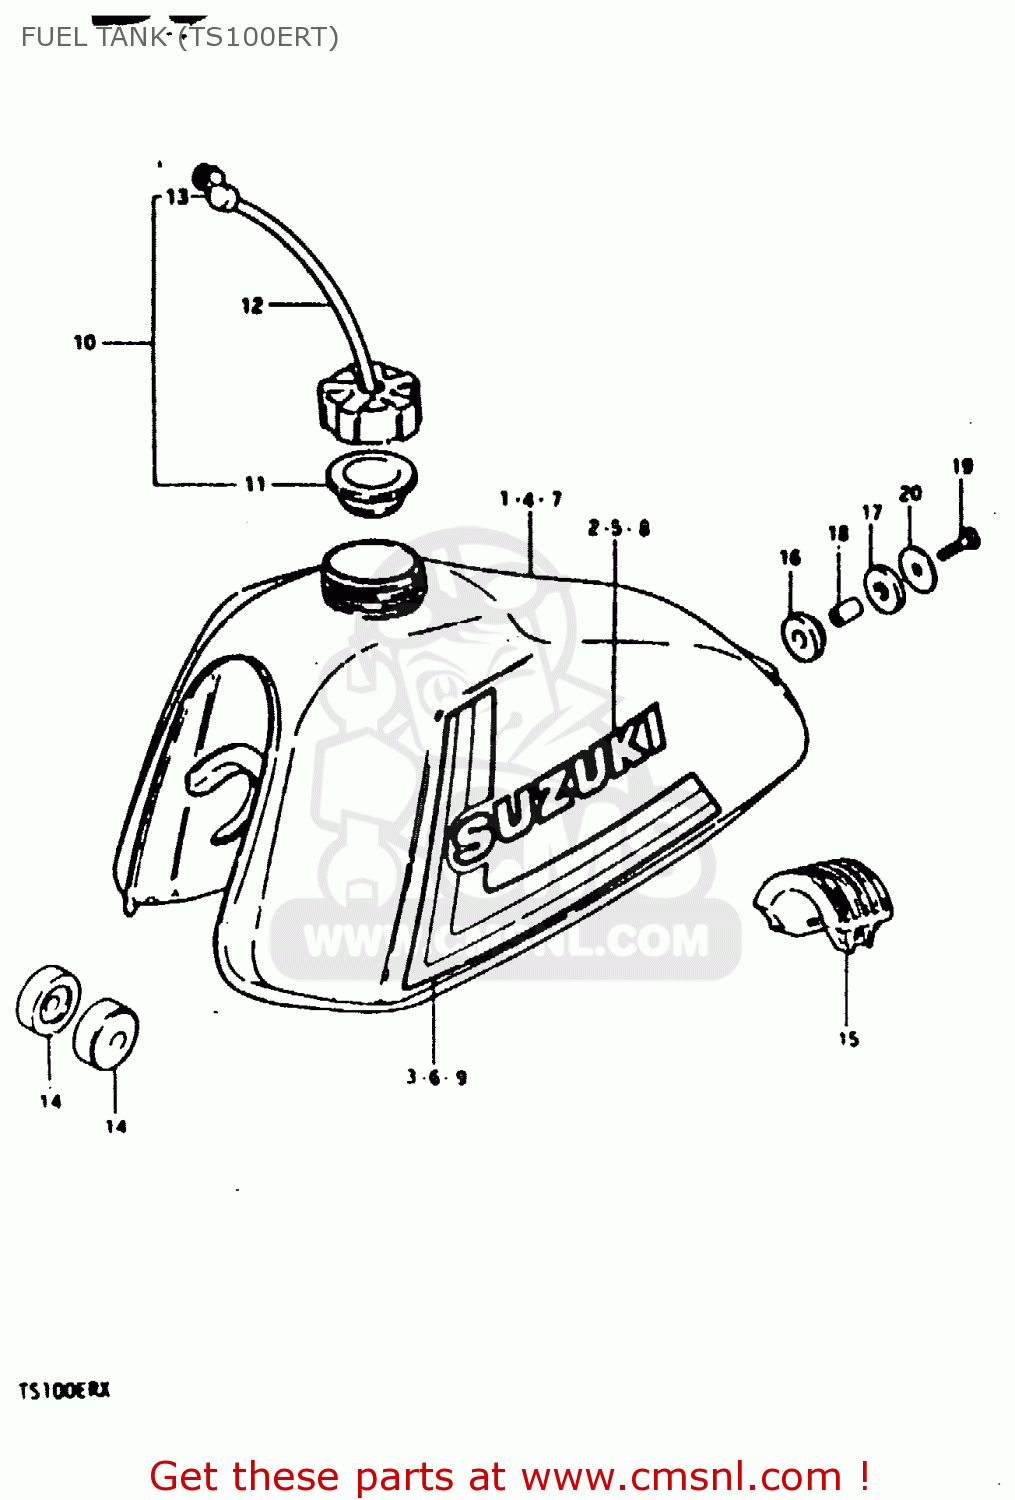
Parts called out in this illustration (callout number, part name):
1	TANK, FUEL (RED)
2	EMBLEM
3	TAPE SET
4	TANK, FUEL (BLUE)
5	EMBLEM
6	TAPE SET
7	TANK, FUEL (WHITE)
8	EMBLEM(BLACK)
9	TAPE SET
10	CAP SET,FUEL TANK
11	GASKET,FUEL TANK CAP (NAS)
12	HOSE
13	CLAMP,FUEL TANK BREATHER HOSE
14	CUSHION
15	CUSHION,FUEL TANK
16	CUSHION
17	CUSHION
18	SPACER(8.5X12X19)
19	BOLT (8X30)
20	WASHER (8.5X29X1.6)
